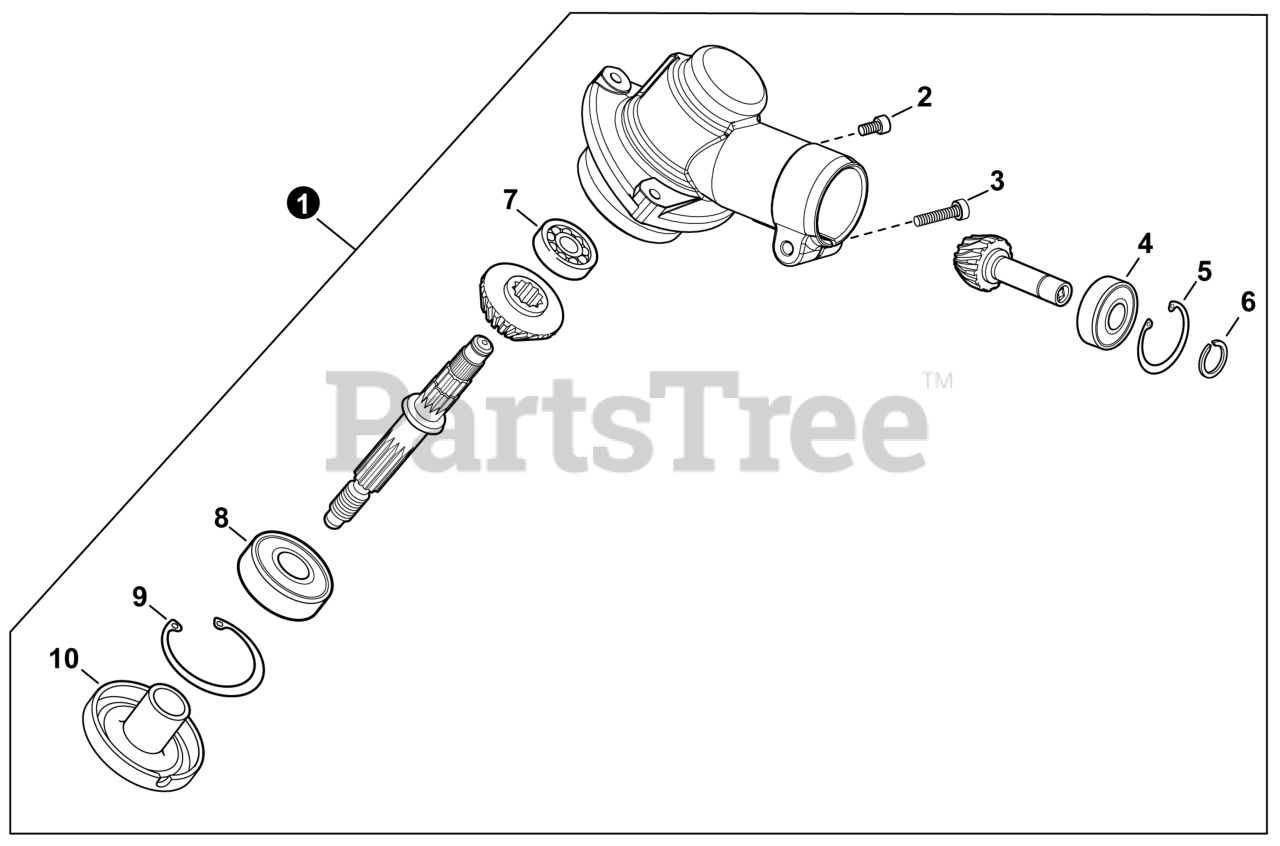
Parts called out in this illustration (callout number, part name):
1	GEAR CASE ASSY
2	BOLT, TORX 5x12
3	BOLT, TORX 5x25
4	BEARING, BALL 609ZA
5	RING, SNAP 24
6	RING, SNAP 9
7	BEARING, BALL 609A
8	BEARING, BALL 6201 2RS
9	RING, SNAP 32
10	PLATE, ADAPTOR - UPPER
